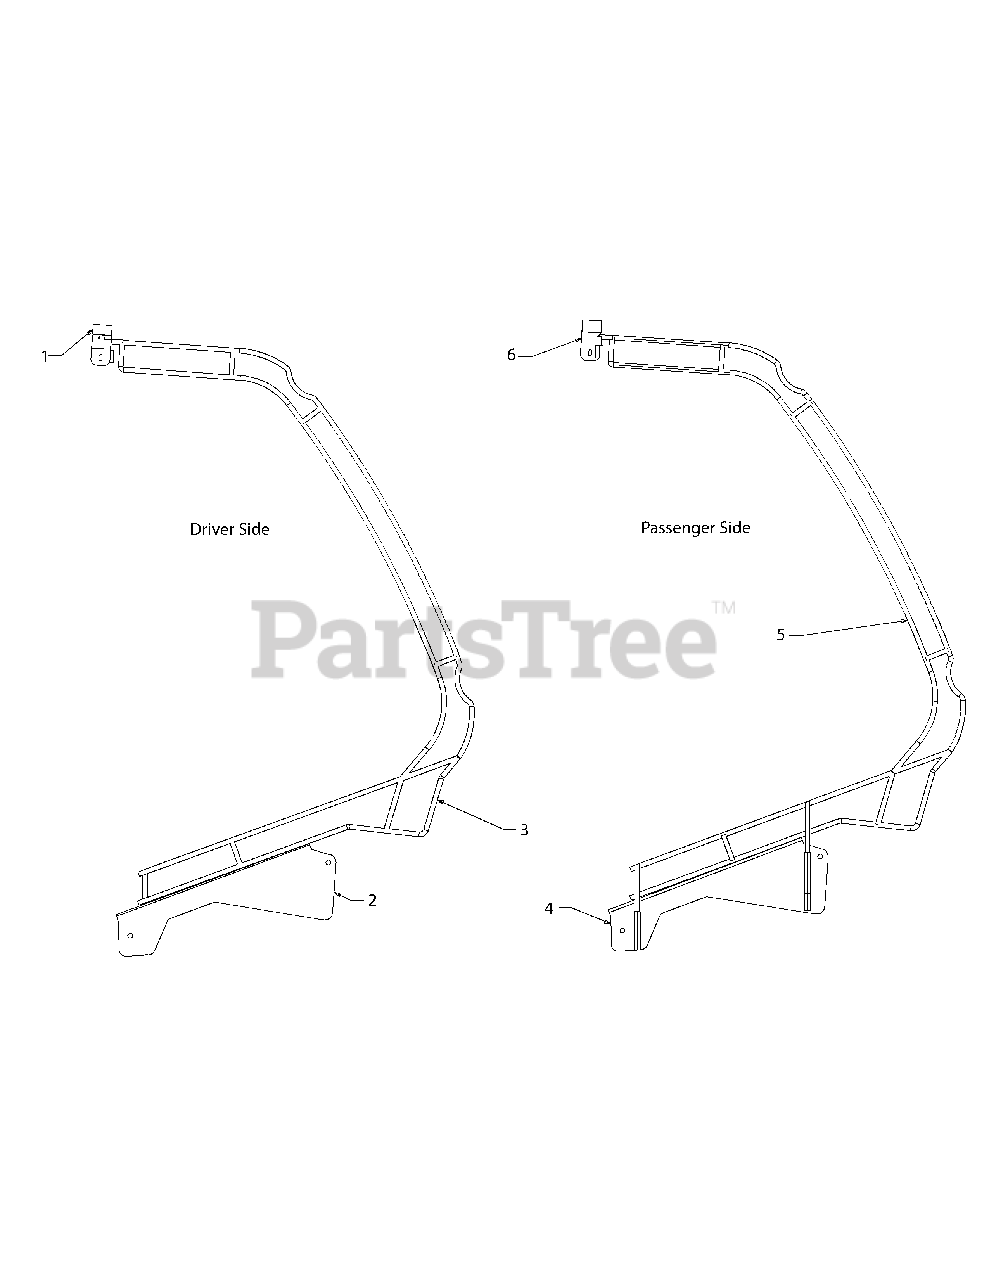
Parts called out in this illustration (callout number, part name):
1	Hinge Assembly, Upper LH (Driver)
2	Door Mount Bracketm LH (Driver)
3	Frame Assembly LH (Driver)
4	Door Mount Bracketm RH (Passenger)
5	Frame Assembly RH (Passenger)
6	Hinge Assembly, Upper RH (Passenger)
